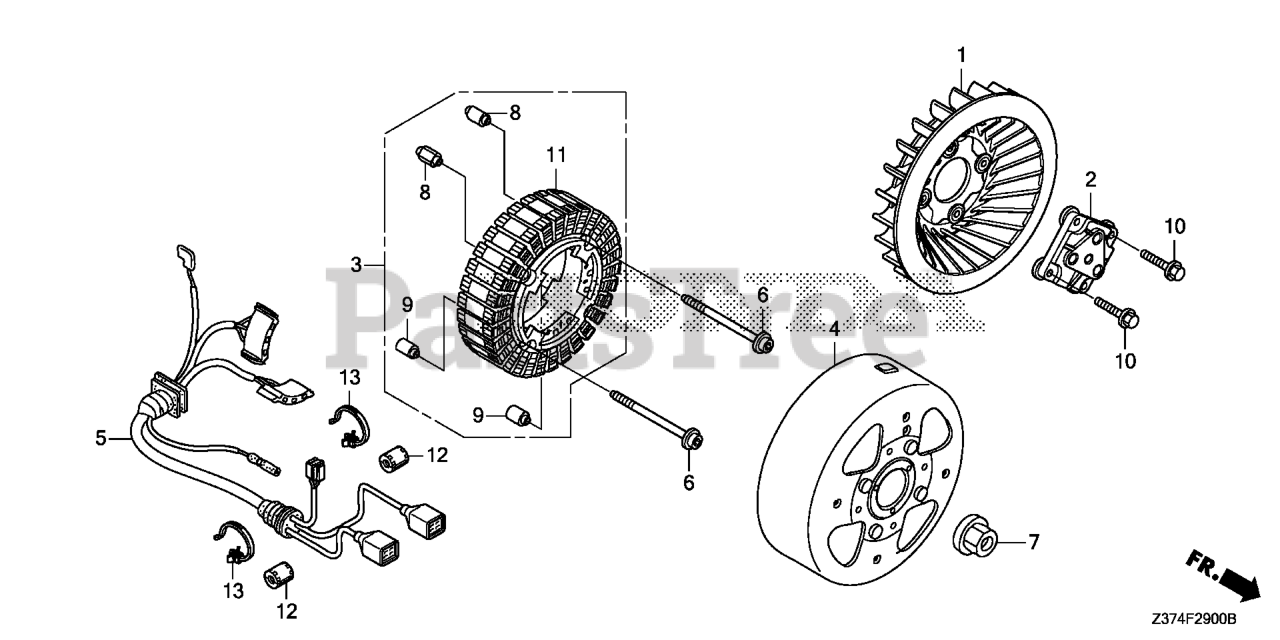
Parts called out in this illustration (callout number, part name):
1	FAN, COOLING
2	ADAPTER, RECOIL PULLEY
3	STATOR ASSY. (NOT AVAILABLE)
5	WIRE HARNESS ASSY., GENERATOR
6	BOLT, FLANGE SOCKET (6X78) (CT200)
7	NUT, SPECIAL (16MM) (1)
8	COLLAR, STATOR (6.3X13X21.5)
9	COLLAR, STATOR (6.3X13X16.5)
10	BOLT, FLANGE (6X35)
11	CORE SET, INSULATED VARNISH (NOT AVAILABLE)
12	FILTER, SUB NOISE (AC)
13	CLIP, SNORKEL HOSE
